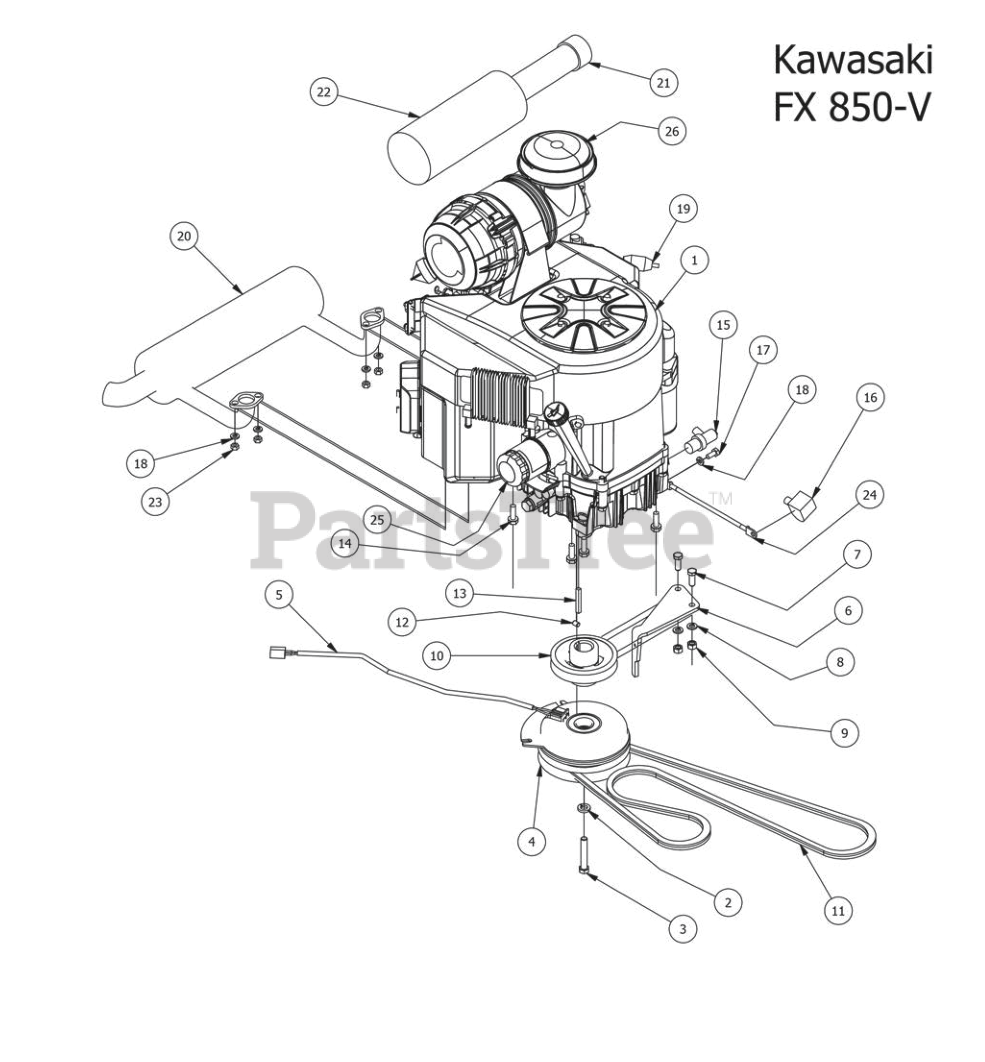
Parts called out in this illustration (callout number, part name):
1	Kawasaki Engine FX-850-V-CS09R
2	7/16" Lock Washer
3	7/16" x 2 1/2" Hex Bolt
4	Clutch Assembly
5	Clutch Pigtail
6	PTO Engager Holder
7	3/8" x 1" Hex Bolt
8	3/8" Lock Washer
9	3/8" Hex Nut
10	4 3/4 Motor Pulley
12	3/8" Set Screw
13	1/4 x 2 Square key Stock
14	3/8 x 1 1/8 bolt
16	Black Boot For ground cable
17	M8x1.20x20MM Hex head bolt
18	5/16" Lock Washer
19	Universal inline Fuel Filter
20	Kawasaki Exhaust
21	Canister Air Filter- Inner
22	Canister Air Filter- Outer
23	M8-1.25 Zinc Nut
24	Starter to chassis cable
25	Kawsaki Oil Filter
26	Kawasaki Rain Cap
